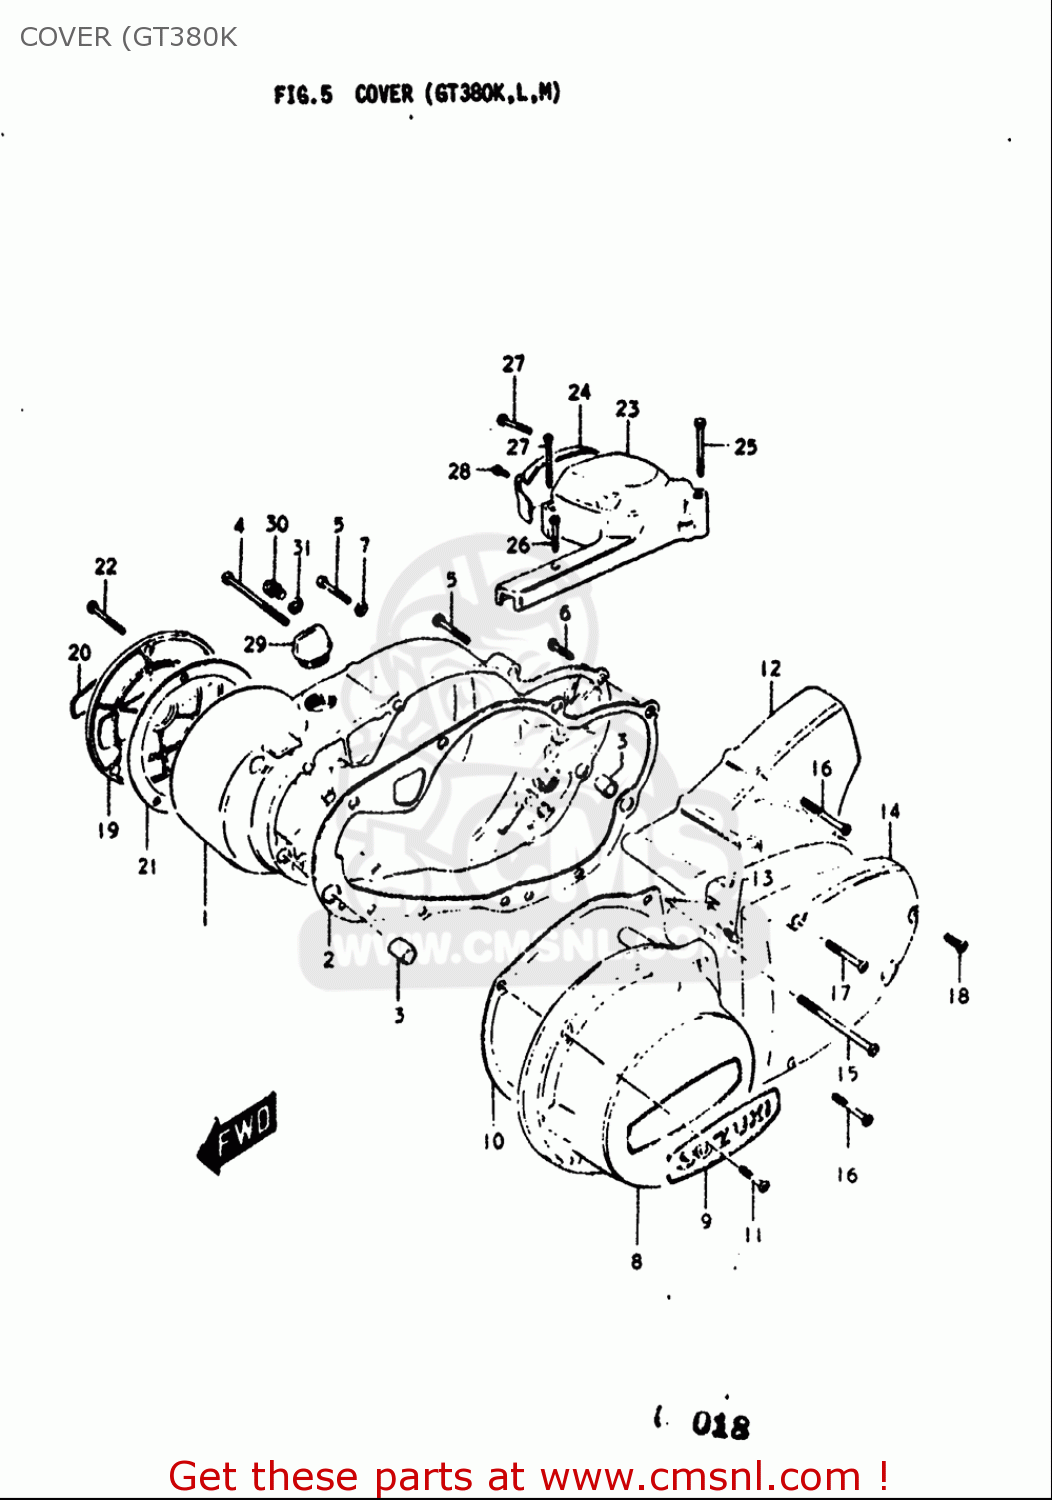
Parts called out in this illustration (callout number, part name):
2	GASKET,CLUTCH COVER (NAS)
3	PIN
4	SCREW
5	SCREW
6	SCREW
7	WASHER(6.5X18X2)
9	EMBLEM,GENERATOR COVER
10	GASKET,MAGNETO COVER (MCA)
11	SCREW
13	NIPPLE
15	SCREW
16	SCREW
17	SCREW
18	SCREW
20	EMBLEM,CONTACT BREAKER CAP
21	GASKET,CONTACT BREAKER CAP (NAS)
22	SCREW
25	BOLT 5X45
26	BOLT
27	SCREW
28	SCREW
29	PLUG
30	SCREW(6X10)
31	GASKET(6.2X11X1) (NAS)
